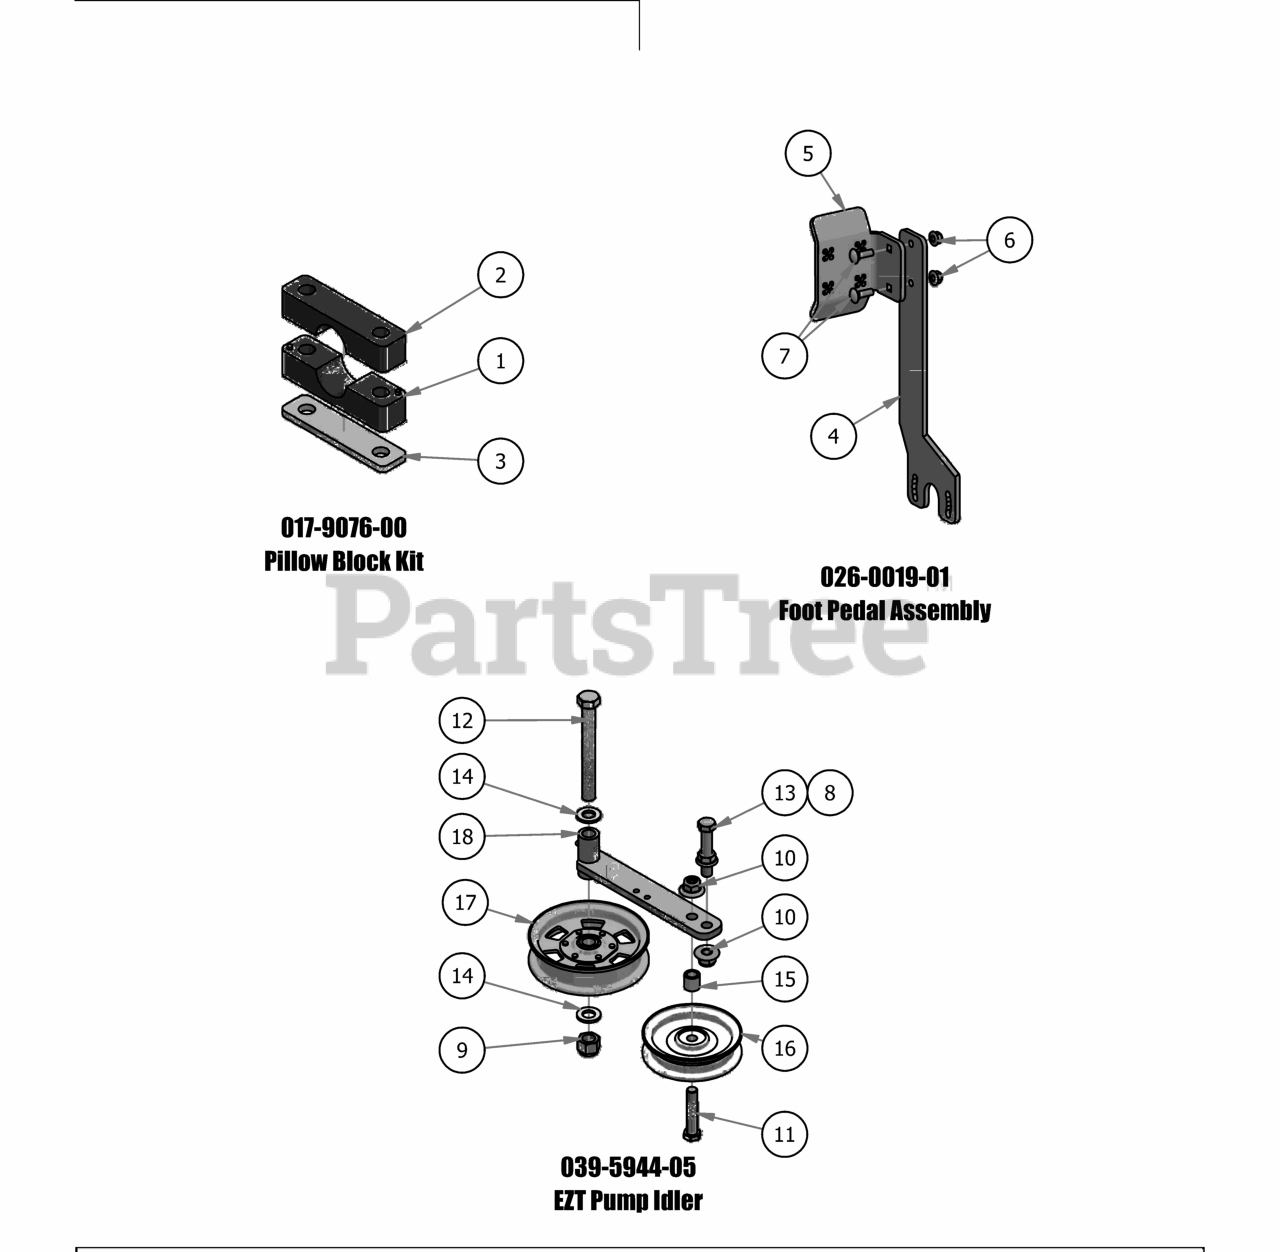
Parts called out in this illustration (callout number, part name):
1	Pillow Block MZ male
2	Pillow Block MZ female
3	Pillow Block Strap
4	2017 MZ/ZT Deck Pedal Lever
5	2017 MZ/ZT Shallow Foot Pedal
6	5/16" Nylon Flange Nut
7	5/16" x 1" Carriage Bolt
8	1/2" Flange Nut
9	5/8 Std NC Nylock Nut
10	1/2-13 Nylon Flange Nut
11	1/2" x 3" Hex Bolt
12	5/8" x 5 1/2 Hex Bolt
13	1/2" x 2 3/4" Hex Bolt
14	.630 ID Plastic Washer
15	Spacer 3/4 OD x 1/2 ID x 3\4 Length
16	4 3/4" Idler Pulley
17	5 3/4 Idler Pulley, 5/8 Bore
18	Deck Idler
